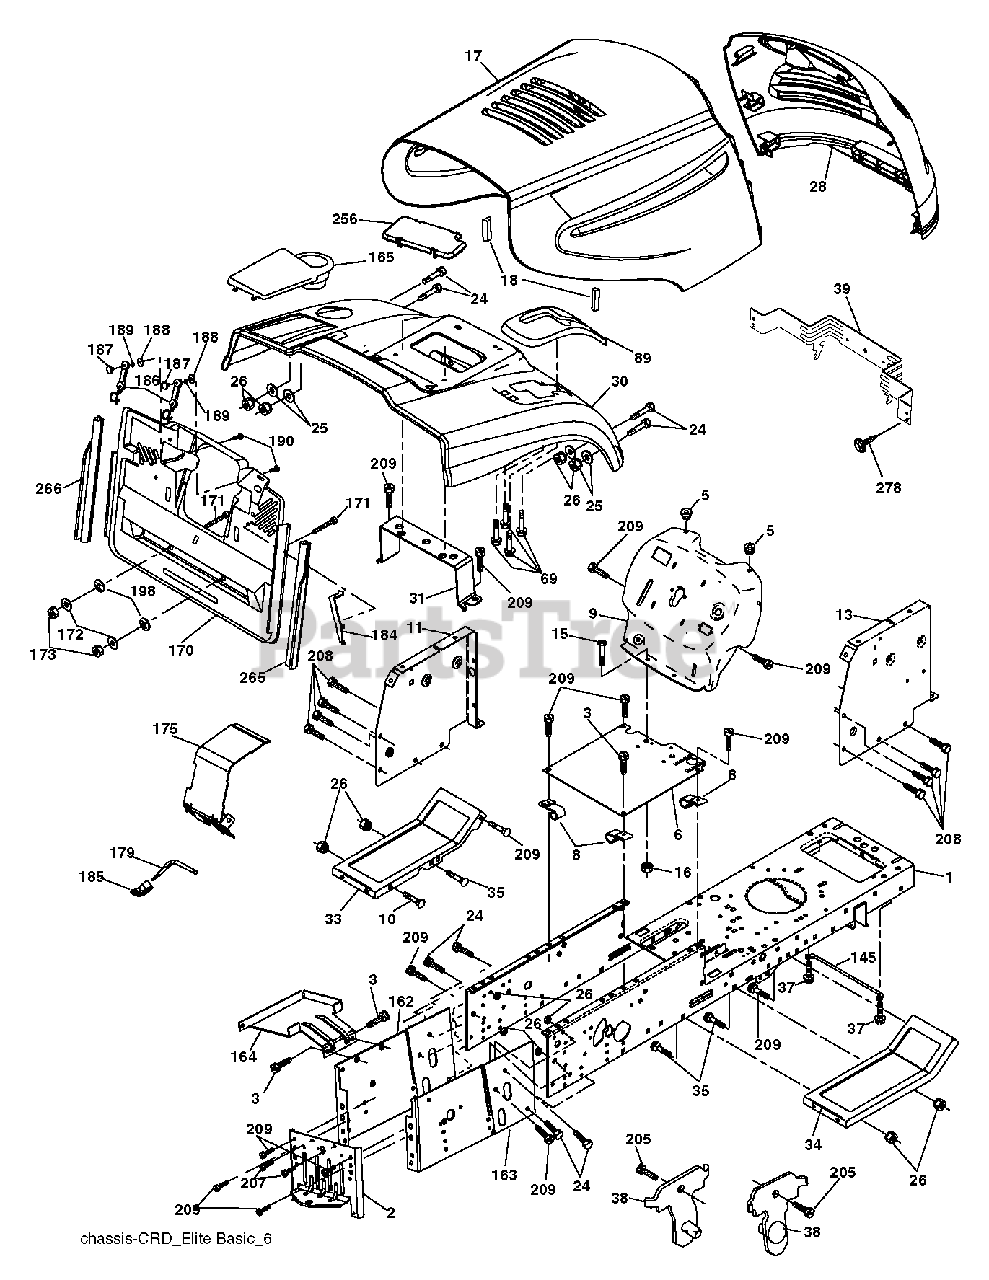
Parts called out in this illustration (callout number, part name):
1	CHASSIS
5	BUMPER.RUBBER.HOOD
8	CLIP,INSULATOR
11	PANEL.DASH.LH.LTX
17	BOOT.STEERING.STEALTH
18	BUMPER.HOOD.LARGE.1.75"
25	WASHER
26	NUT
31	BRACKET SUPPORT FENDER
33	FOOTREST.RH.VGT
37	SCREW LT
39	BRACKET PIVOT
69	SCREW.HI-LO.CONSOLE
145	ROD.PIVOT.HOOD
164	SUPPORT
171	BOLT
184	BRACKET.ACTUATOR.BAGGER.SRD
185	KNOB.BRAKE.PARKING.ROD
186	LATCH ASSY
187	WELDNUT
189	LOCKWASHER
205	SCREW LT
207	SCREW, 5/16-18 X 1/2
208	SCREW 3/8-16X1/2
209	SCREW, 3/8-16X3/4
278	SCREW.#10 X 0.750.BOS (2 2)
